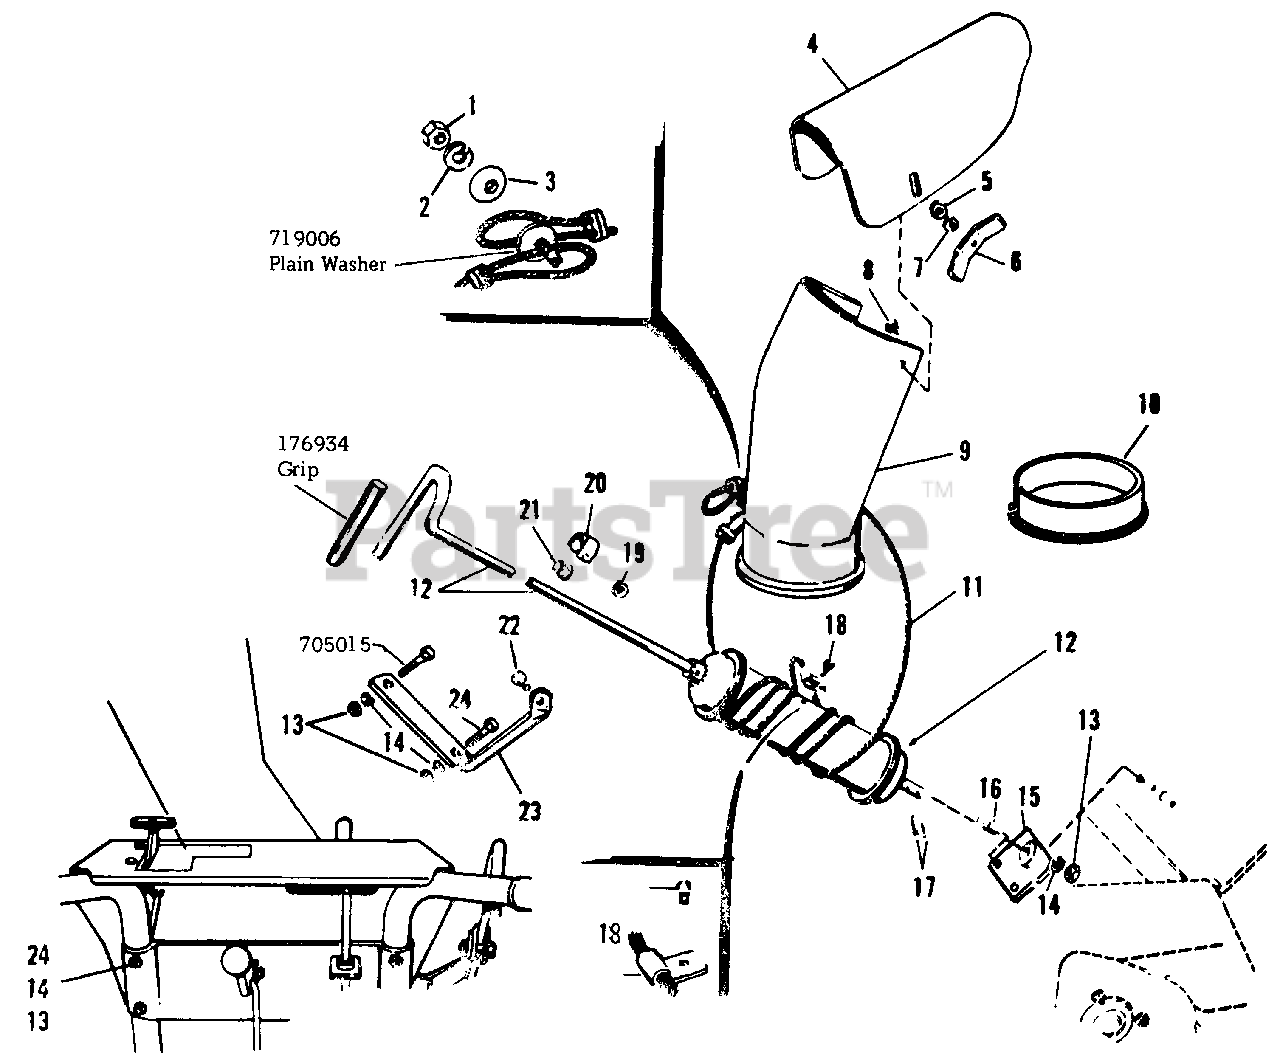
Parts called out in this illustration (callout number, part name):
1	Hex Nut, Full, 5/16"-18" NC (For "725" Only-Rear)
2	Lockwasher, External 1/4" (Mfg. Nos. 953 & 954)
3	WASHER, Cup
4	EXTENSION, Spout
5	Lock Washer, Special, Hexagon, 3/8"
6	NUT, Wing, 5/16-18
7	Plain Washer, 5/16" (Mfg. No. 920)
8	Bolt, Carriage, 5/16"-18 NC x 3/4" lg., Short Square Neck
9	SPOUT-assembly
10	LINER (990430 & 990560 Only)
11	Cable Assembly
12	TUBE ASSY., Spout Control
13	Hex Nut, 1/4"-20 (Mfg. Nos. 953 & 954)
14	Lock Washer, 1/4" (Not used on 308 & 314)
16	Screw, Cap, Hex., 1/4"-20 N.C. x 5/8" lg.
17	Pin, Cotter, 1/8" x 3/4" lg.
18	Hex Screw, Washer Hd., 1/4"-20 x 3/8" lg. Taptite
19	Nut, Lock, Hex Hd., Full, 5/16"-18 N.C.
20	GUIDE-rod
21	LINER-guide
22	Hex. Hd. Capscrew, 5/16"-18 N.C. x 1-1/4" lg.
23	SUPPORT-adjusting rod spout
24	Rd. Hd. Cap Screw, 1/4"-20 x 1 3/4" lg.
